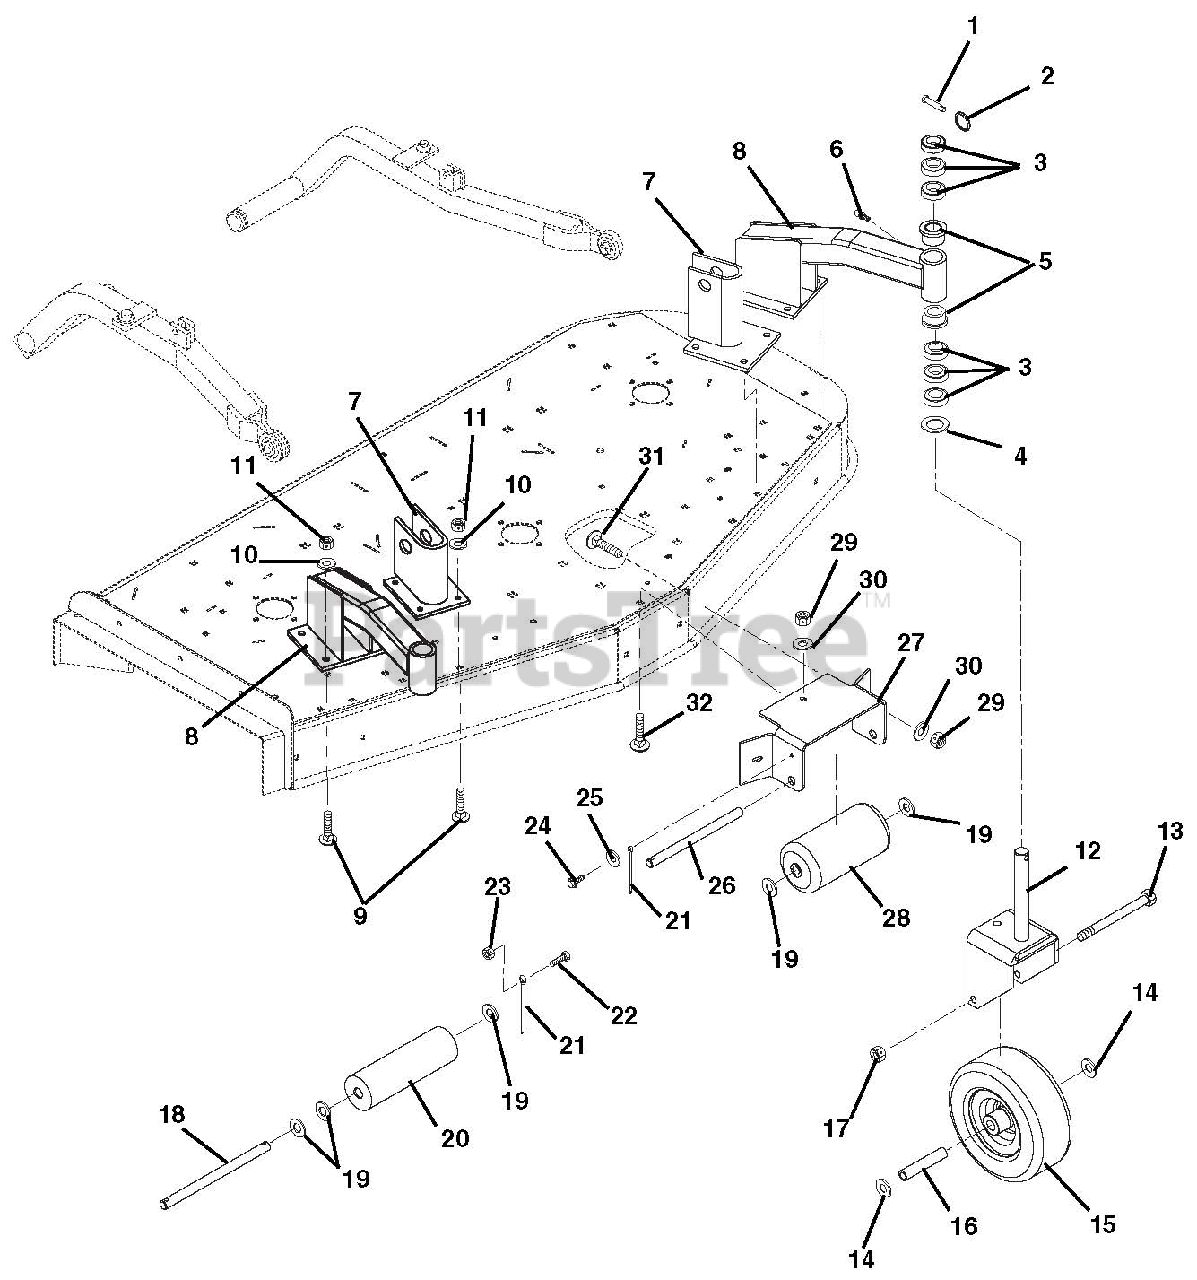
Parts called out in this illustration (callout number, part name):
1	PIN-CLEV .31 X 2.62 GR5 YWZC
2	RG-RTNG-EXT 1.062 X 1.25 YWZC
3	BSHG-SLV 1.04X1.75X.500 ST
4	WSHR-HDND-THRUST 1.00X1.55X.03
5	BSHG-FLG1.020X1.385X.75X1.75NY
6	FTG,LUBE, .25-28 SELF THREAD
7	WMT, LIFT ARM MOUNT
8	WMT, CASTER WHEEL SUPPORT
9	BLT-RDHDSQNK .50-13X1.50 G5YZ
10	WSHR-FL-STL.531X1.06X.095YWZC
11	NUT-LK-NYL .50-13 YWZC
12	WLDMT, CASTER FORK
13	BLT-HEX .50-13X6.00 GR5 YWZC
14	WSHR-HDND-THRST .760X1.25X.094
15	TIRE, 11X4.00
16	SPACER .532X.750X4.47
17	NUT-LK-CTR .50-13 YWZC
18	SHAFT,CENTER ROLLER
19	WSHR-FL-STL.656X1.31X.095 YWZ
20	RLR,GAGE
21	PIN-CTR .25X2.00 YWZC
22	BLT-HEX .25-20X.75 GR5 YWZC
23	NUT-LK-NYL .250-20 YWZC
24	SCR-TAP .25-20X.50 HWH TR YWZ
25	WSHR-FL-STL.281X.62X.065 YWZC
27	BRACKET, ANTI SCALP ROLLER
29	NUT-LK-NYL .38-16 YWZC
30	WSHR-FL-STL.406X.812X.065 YWZ
31	BLT-RDHDSQNK .38-16X1.00 G5YZ
32	BLT-RDHDSQNK .38-16X1.25 G5YZ
